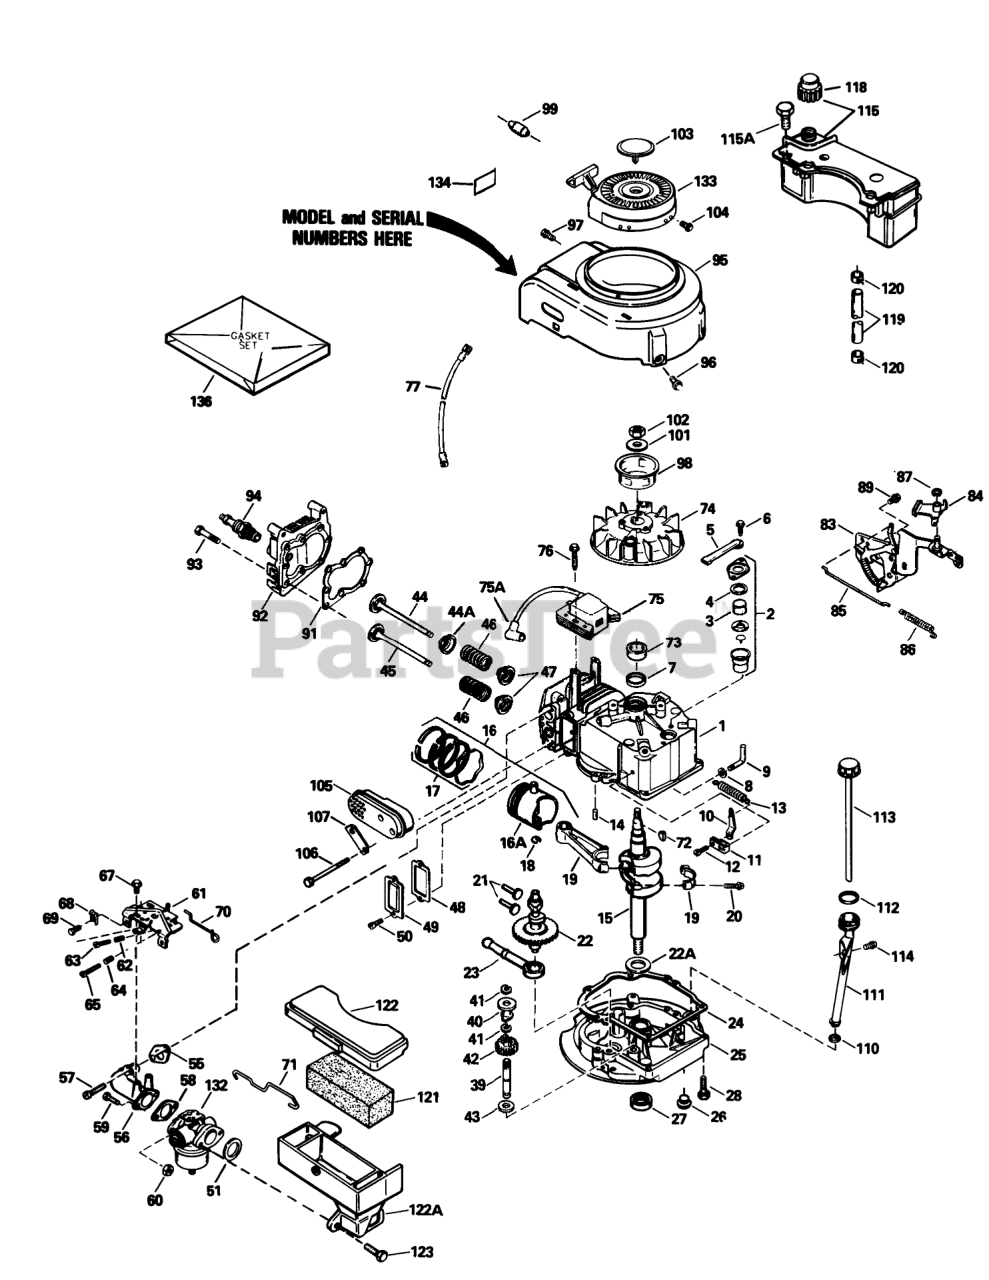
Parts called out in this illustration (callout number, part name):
1	Cylinder Assembly (Incl. Ref. #7 & 14)
2	Breather Assembly (Incl. Ref. #3, 4, 5 & 6)
3	Element-Breather
4	Gasket-Breather
5	Tube, Breaker
6	Screw (10-24 x 9/16)
7	Seal-Oil
8	Washer-Flat
9	Rod, Governor (Incl. Ref. #8)
10	Governor Lever
11	Clamp-Lever, Governor
12	Screw
13	Spring Governor
14	Pin-Dowel
15	Crankshaft Assy.
16	Piston, Pin & Ring Assy.(STD.)(Incl. Ref. #16A, 17 & 18)
16	Piston, Pin & Ring Assy.(.010 oversize)(Incl. Ref. #16A, 17 & 18)
16	Piston, Pin & Ring Assy.(.020 oversize)(Incl. Ref. #16A, 17 & 18)
16A	Piston & Pin Assy. (Std.)(Incl. Ref. #18)
16A	Piston & Pin Assy.(.010 oversize)(Incl. Ref. #18)
16A	Piston & Pin Assy.(.020 oversize)(Incl. Ref. #18)
17	Ring Set-Piston (Std.)
17	Ring Set, Piston(.0100versize)
17	Ring Set (.020" OS)
18	Ring-Retaining, Piston Pin
19	Rod Assy., Connecting (Incl. Ref. #20)
20	Bolt-Rod, Connecting
21	Lifter-Valve
22	Camshaft(Mech.Comp. Release)
22A	Washer-Thrust
23	Oil Pump ASM
24	Gasket
25	Flange, Mounting (Incl. Ref. #26, 27 & 39)
26	Plug Oil Drain
27	Seal-Oil
28	Screw (1/4-20 x 1-1/4)
39	Shaft-Governor
40	Spool-Governor
41	Ring-Retaining
42	Gear Assy., Governor (Incl. Ref. #43)
43	Washer-Flat
44	Valve, Intake (Std.)(Incl. Ref. #47)
44	Valve, Intake (1/32" oversize)(Incl. Ref. #47)
44A	Seal Assy., Intake
45	Valve, Exhaust (Std.)(Incl. Ref. #47)
45	Valve, Exhaust (1/32" oversize)(Incl. Ref. #47)
46	Spring-Valve
47	Cap-Valve, Spring
48	Gasket-Breather
49	Cover-Valve
51	Gasket-Cleaner, Air
55	Gasket-Intake
56	Pipe, Intake (Incl. Ref. #55)
57	Screw (1/4-20 x 1)
59	Screw (1/4-28 x 7/8)
60	Nut and Lock Washer (1/4-28)
61	Bracket Assy., Control (Incl. Ref. #62 thru 65)
62	61709/GIL1515A/95-5
63	Screw
64	Spring-Compression
65	Screw
67	Screw (10-24 x 9/16)
68	Conduit
69	Screw (10-32 x 3/8)
70	2035A67 ADD.ASSEMBL
71	Link-Throttle
72	Key-Flywheel
74	Flywheel
75	Solid State
75A	Cover-Spark Plug
76	Screw
77	Ground Wire
83	Bracket-S.E. Brake
84	Lever-Brake
85	Link-Control
86	Spring-Extension
87	Ring-Retaining
89	Screw (1/4-20 x 3/8)
91	63573 GIL 42 SNWTHW
92	Head-Cylinder
93	Screw (5/16-18x1-1/2)
94	Spark Plug-Resistor (R J19 L M)
95	Housing-Blower
96	Screw (1/4-20 x 1/2)
97	Screw (10-24 x 9/16)
98	Hub-Starter
99	Retainer-Starter Rope
101	Washer-Belleville
102	Nut-Flywheel
103	Plug Starter
104	Screw, Hex Hd.
105	MufflerAssy. (Incl. Ref. #106)
107	Plate-Lock
111	Oil Fill Tube
113	Dipstick
114	Screw (10-32 x 1/2)
115	Shroud & Tank Assy. (Incl. Ref. #118 & 120)
115A	Screw (10-32 x 35/64)
118	Cap-Fuel
119	Line-Fuel
120	Clamp-Line, Fuel
121	Filter-Air Cleaner
122	Cover-Air Cleaner
122A	Body Air cleaner
132	Carburetor (Incl. Ref. #58)
133	Starter-Rewind
134	Decal-Primer
136	Gasket Set (Incl. items marked )
